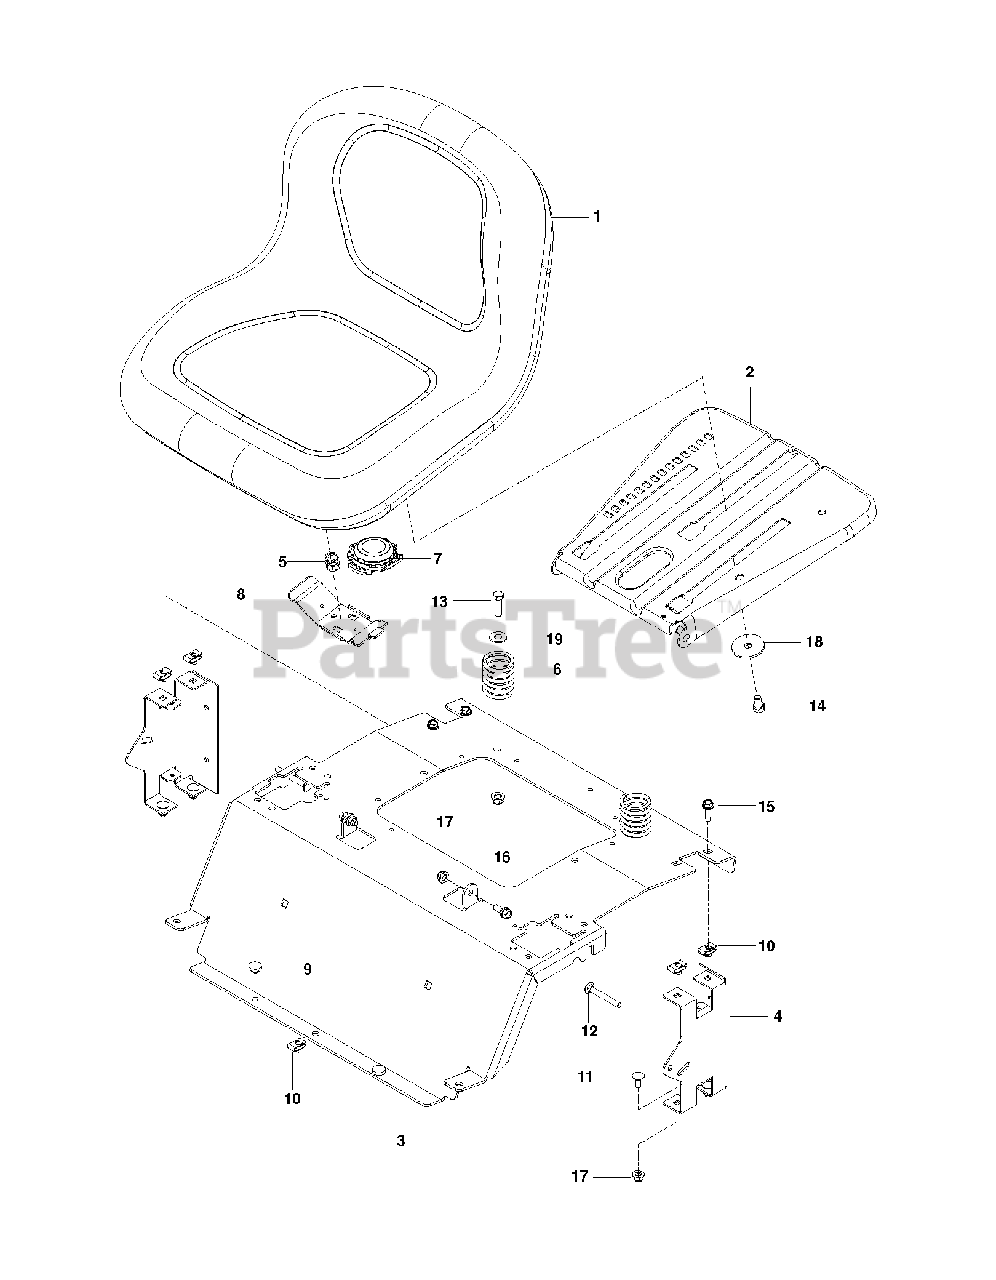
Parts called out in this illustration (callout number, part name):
1	SEAT.TH150.MS498.GRY.HUSQ.TEX
2	PAN.ASM.SEAT.3PT
3	SUPPORT SEAT ORANGE
4	SUPPORT REAR SEAT BLACK
5	SPRING.LATCH.SEAT.TEX
7	SWITCH, SEAT N/C
8	HANDLE.SLIDE.SEAT.TEX.BLACK
9	GROMMET, BUMPER
10	U-CLIP 5/16-18 NUT RETAINER
11	BOLT 5/16C X 3/4" CARRIAGE
12	RHSNB 5/16-18 X 2-1/2 GR5 ZD
13	HCS 3/8C X 1 1/4 GR5
14	HCS 3/8-16 X 5/8 GR 5 ZD
15	BOLT 5/16-18 X 3/4
16	BOLT, SHOULDER
17	5/16-18 NYLOC FLANGE NUT
18	WASHER, 3/8 SPEC
19	RP WASHER 3/8 FLAT
